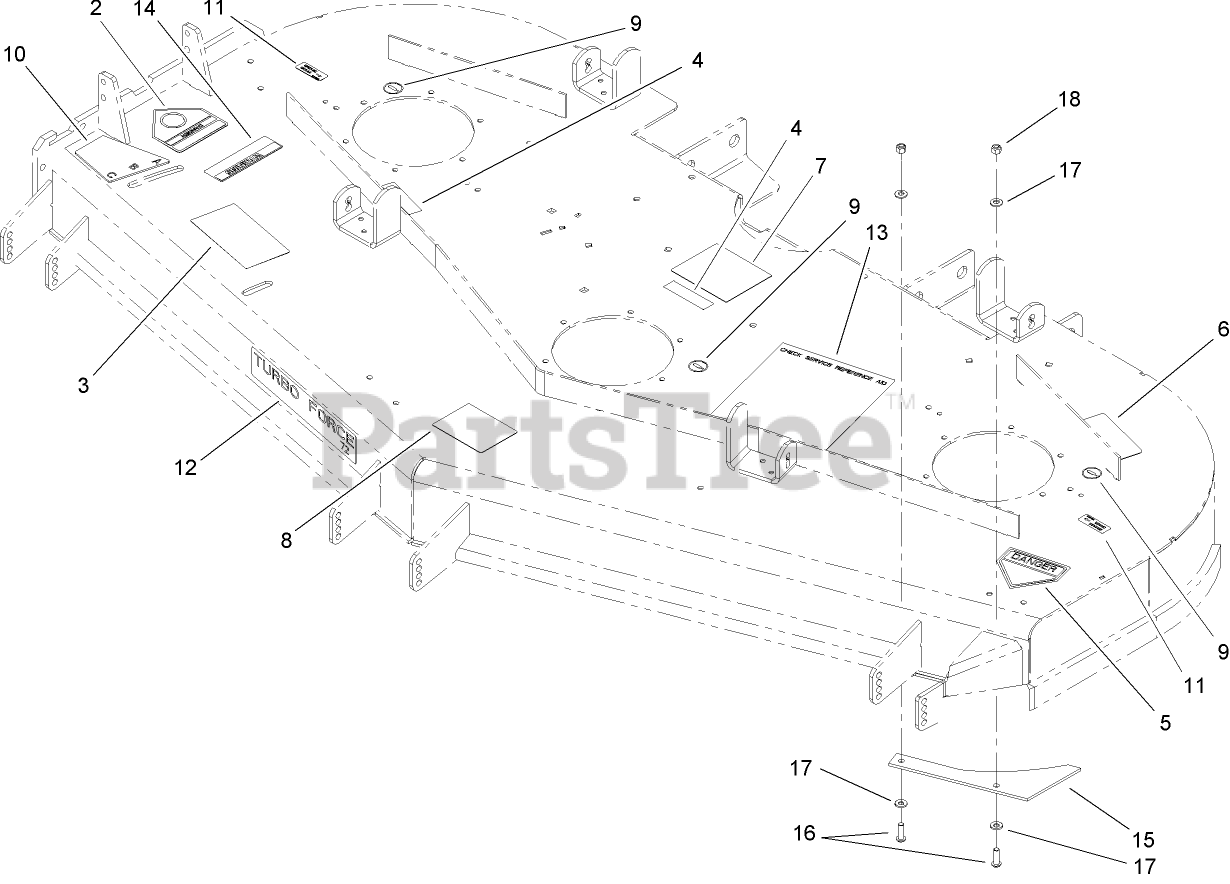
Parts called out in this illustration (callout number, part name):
2	DECAL-DANGER
3	DECAL-DANGER, THROWN OBJECT
4	DECAL-COVER, MISSING
5	DECAL-DANGER
6	DECAL-TORQUE
7	Decal-Routing, Belt
8	DECAL-SCALP, ANTI
9	DECAL-GREASE
10	DECAL-ADJUSTMENT, BAFFLE
11	Decal-Grease
13	Decal-Service, Check
14	DECAL-WARNING
15	PLATE-TURBO
16	SCREW-HSBH
17	WASHER-SPRING
18	NUT-LOCK, NI
